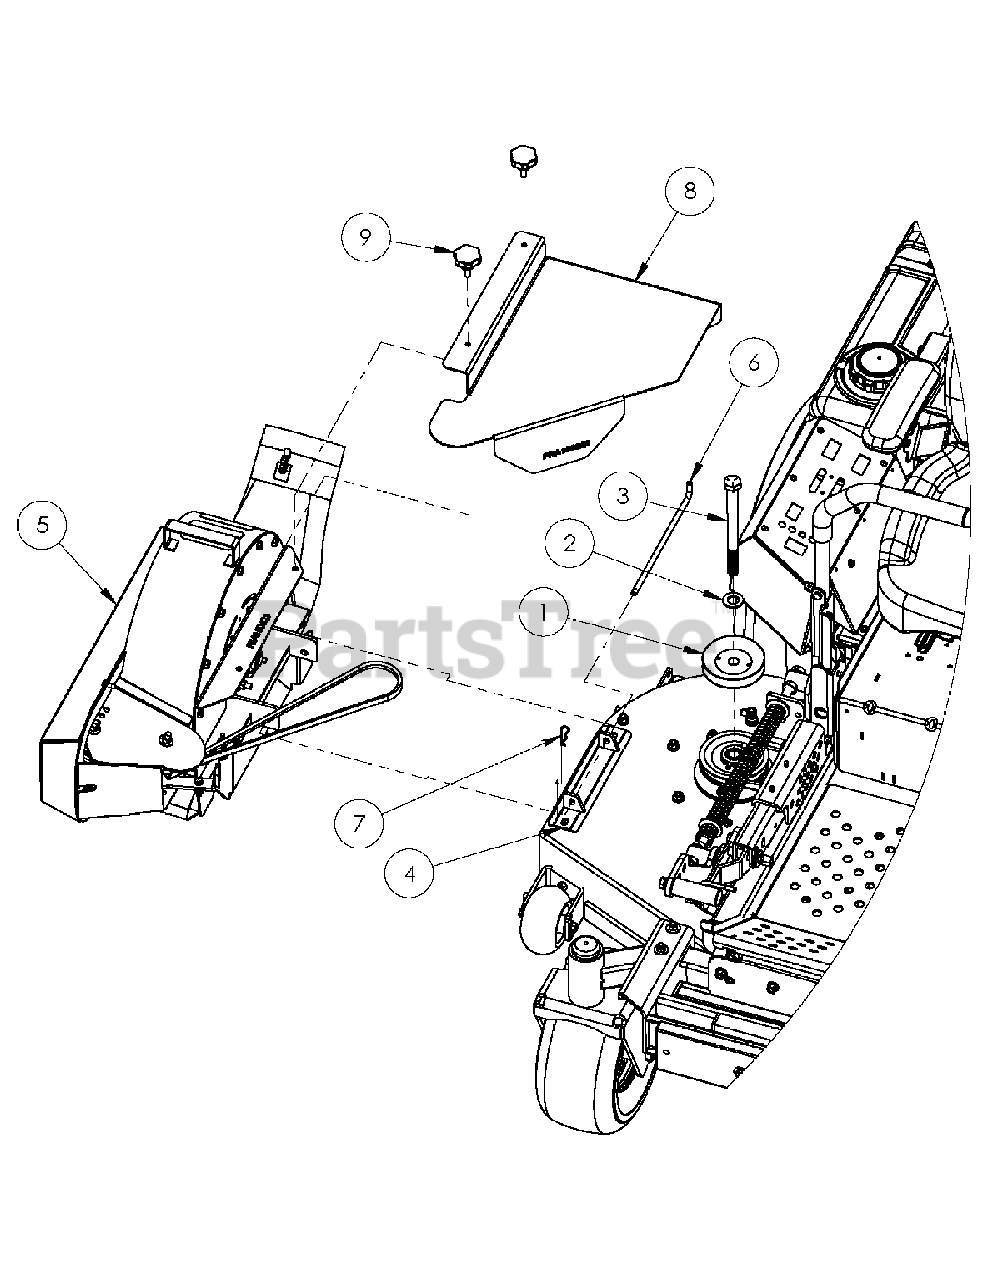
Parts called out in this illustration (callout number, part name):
3	CAP SCREW 3/4-16 X 8 3/4" LONG
4	DECK MOUNTING BRACKET
6	MOUNTING PIN
8	BELT COVER DECK
9	RELEASE KNOB
